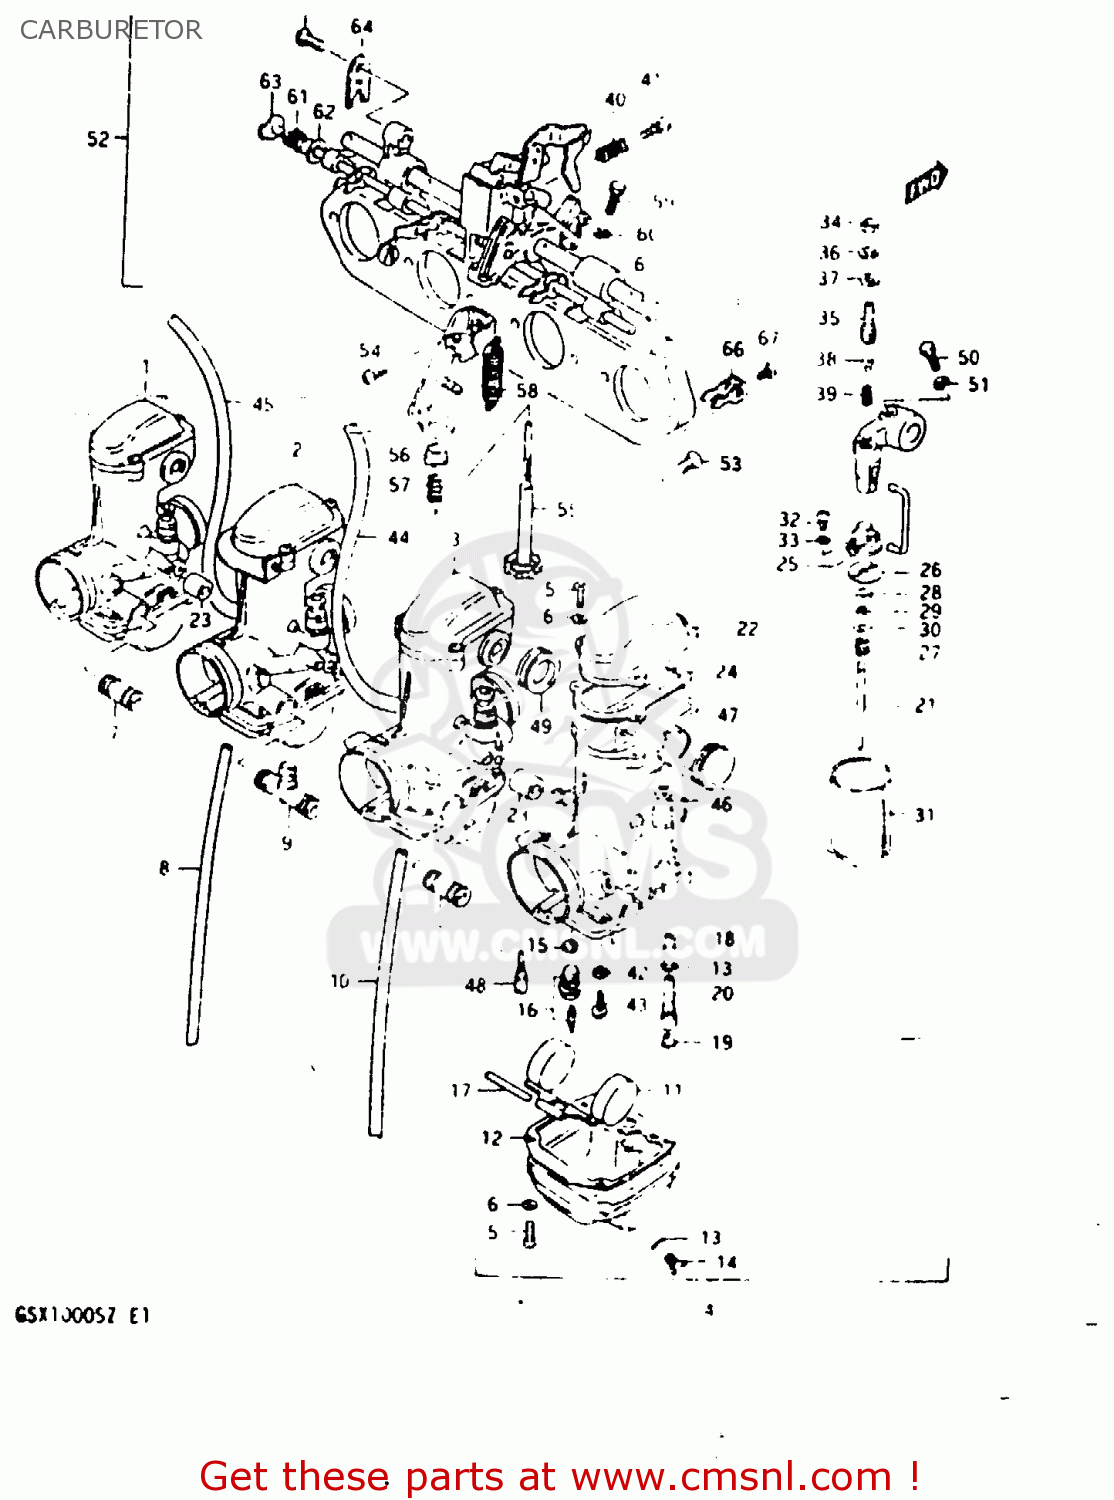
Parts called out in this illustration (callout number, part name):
1	CARBURETOR, LH
2	CARBURETOR, ML
3	CARBURETOR, MR
4	CARBURETOR, RH
5	SCREW
6	LOCK WASHER
7	NIPPLE
8	HOSE
9	NIPPLE
10	HOSE (L:450)
11	FLOAT
12	GASKET,FLOAT CAHMBER
13	O RING
14	SCREW
15	FILTER
16	VALVE ASSY,NEEDLE
17	PIN,FLOAT
18	NEEDLE, JET (5DL82-3)
19	JET
20	HOLDER, JET
21	JET,NEEDLE
22	COVER, TOP
23	HOSE
24	GASKET (NAS)
25	CONNECTOR
26	PLATE,THROTTLE VALVE
27	SPRING
28	RING
29	CLIP
30	WASHER,JET NEEDLE
31	THROTTLE VALVE
32	SCREW
33	LOCK WASHER
34	NUT
35	ADJUSTER
36	WASHER
37	WASHER,STARTER SHAFT
38	PIN,CARBURETOR
39	SPRING,CARBURETOR
40	SPRING
41	ADJUSTER
42	PLATE
43	SCREW 4X6
44	HOSE 4.5X8X390
45	HOSE 4.5X8X390
46	RING
47	PIPE,DELIVERY
48	JET
49	SEAL
50	BOLT
51	LOCK WASHER
52	CONTROL ASSY
53	SCREW
54	SCREW
55	ADJUSTER
56	CAP
57	SPRING
58	SPRING,THROTTLE RETURN
59	BOLT
60	LOCK WASHER
61	SPRING
62	WASHER
63	SHAFT, STARTER
64	PLATE
65	SHAFT
66	LEVER
67	SCREW
